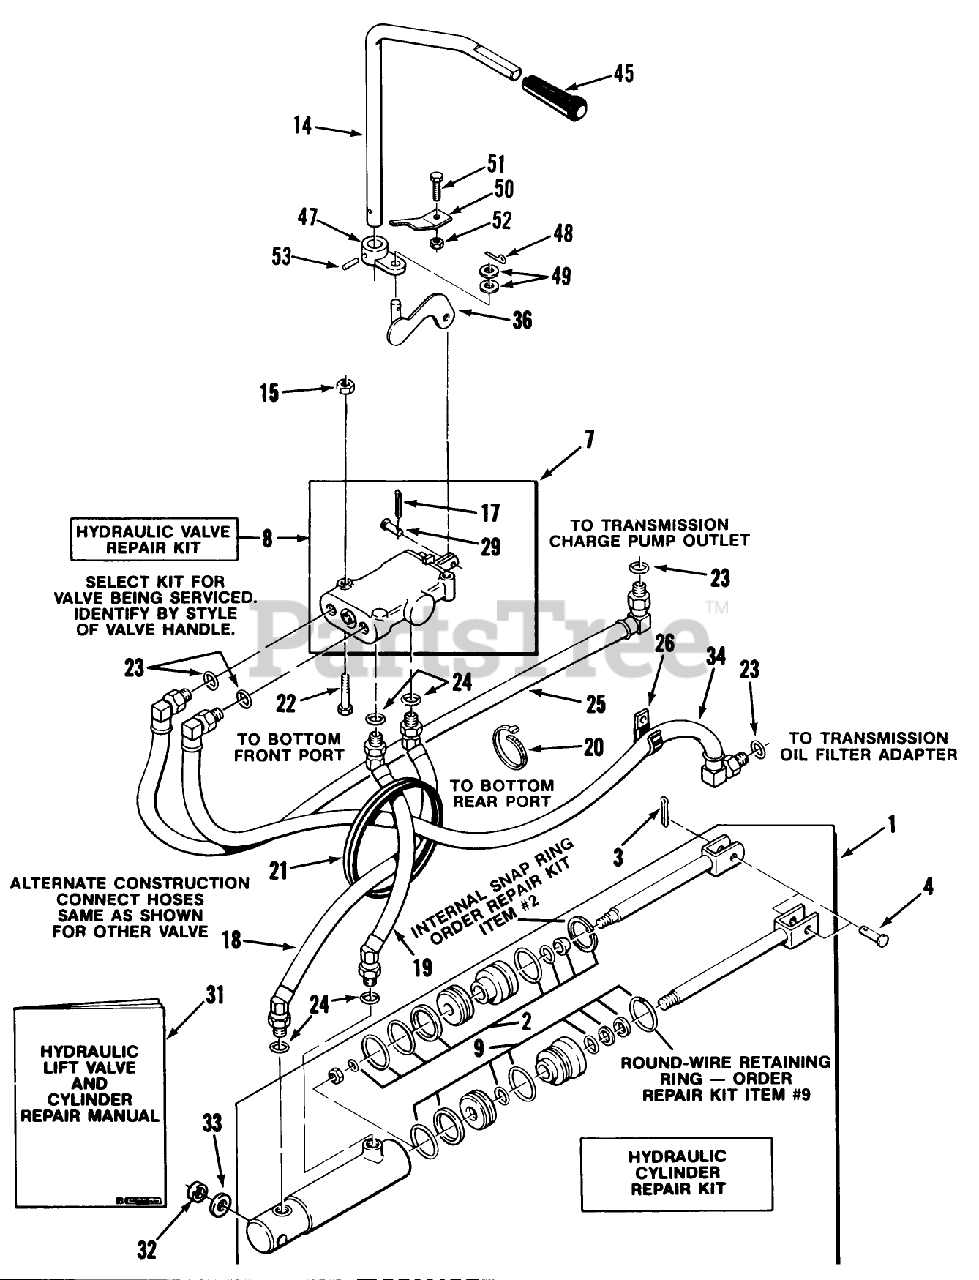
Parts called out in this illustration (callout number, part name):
2	S/A O-RING&GASKET AS
4	CLEVIS PIN
14	Valve Handle
21	GROMMET
24	O RING
26	CLIP
31	Repair Manual
33	WASHER
47	ARM-CONTROL
49	WASHER 5/16 SAE
50	BRACKET-CONTROL R *B
53	SPIROL PIN 7/32X7/8
